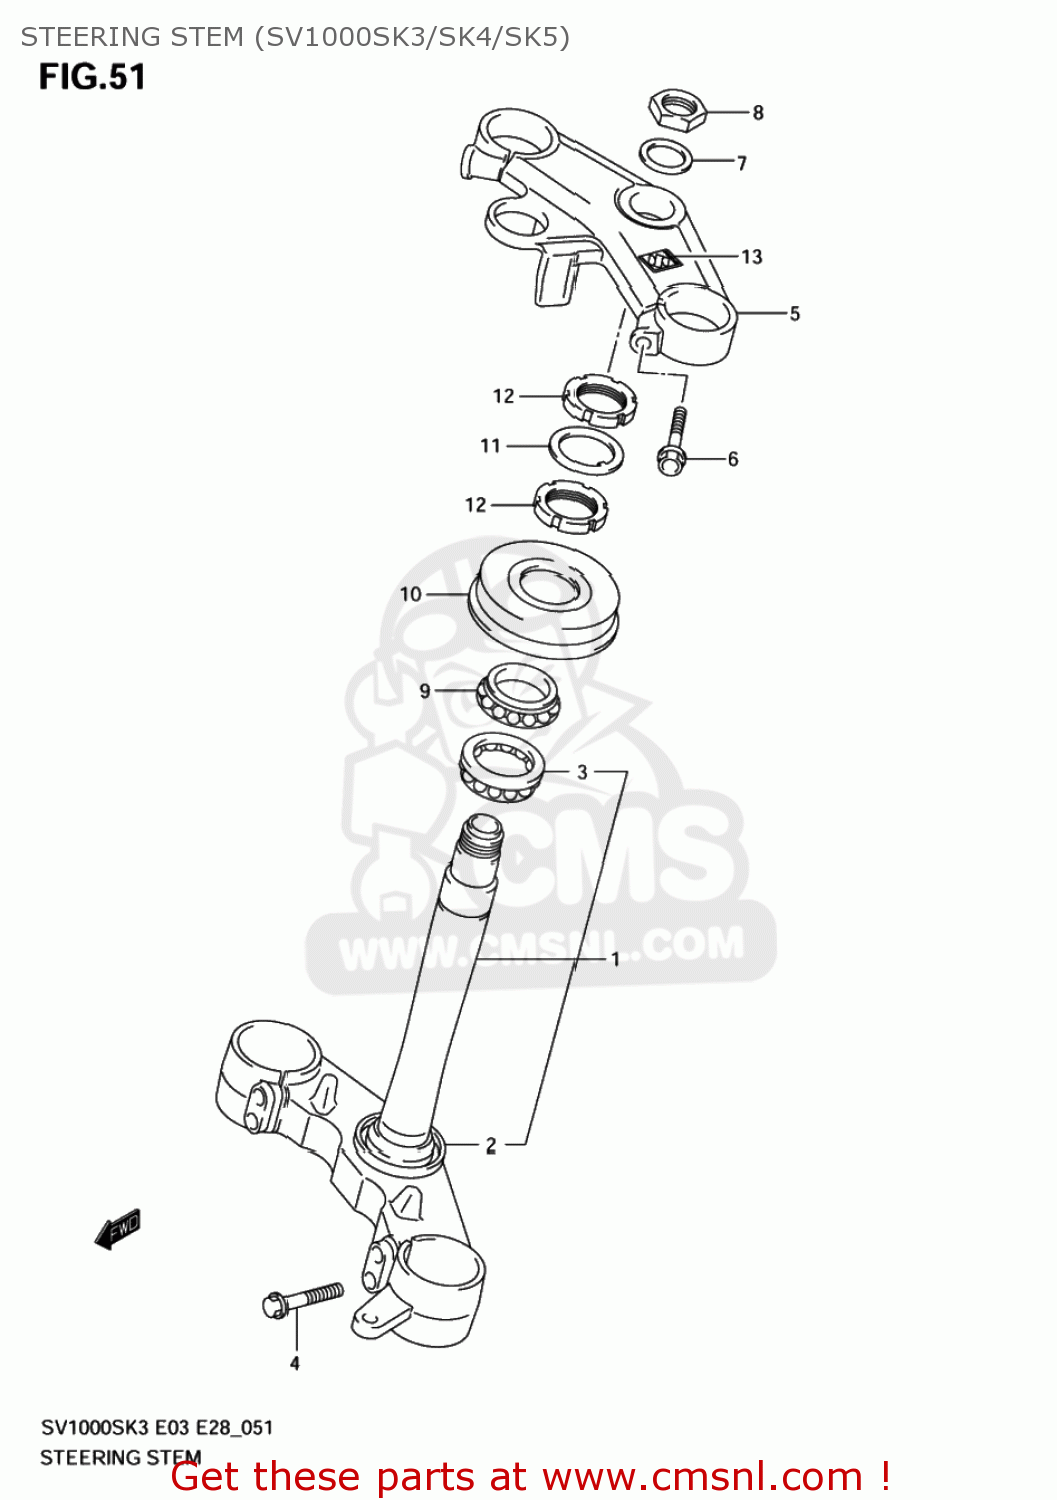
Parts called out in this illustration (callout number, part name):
1	STEM,STEERING
2	SEAL,STEERING LWR
3	BEARING(30X55X17)
4	BOLT
5	HEAD,STEERING STEM
6	BOLT
7	WASHER,STEM HEAD(24.5X34X1.6)
8	NUT
9	BEARING(30X55X17)
10	SEAL,STEERING UPR DUST
11	WASHER,STEERING STEM
12	NUT,STEERING STEM
13	EMBLEM,S
